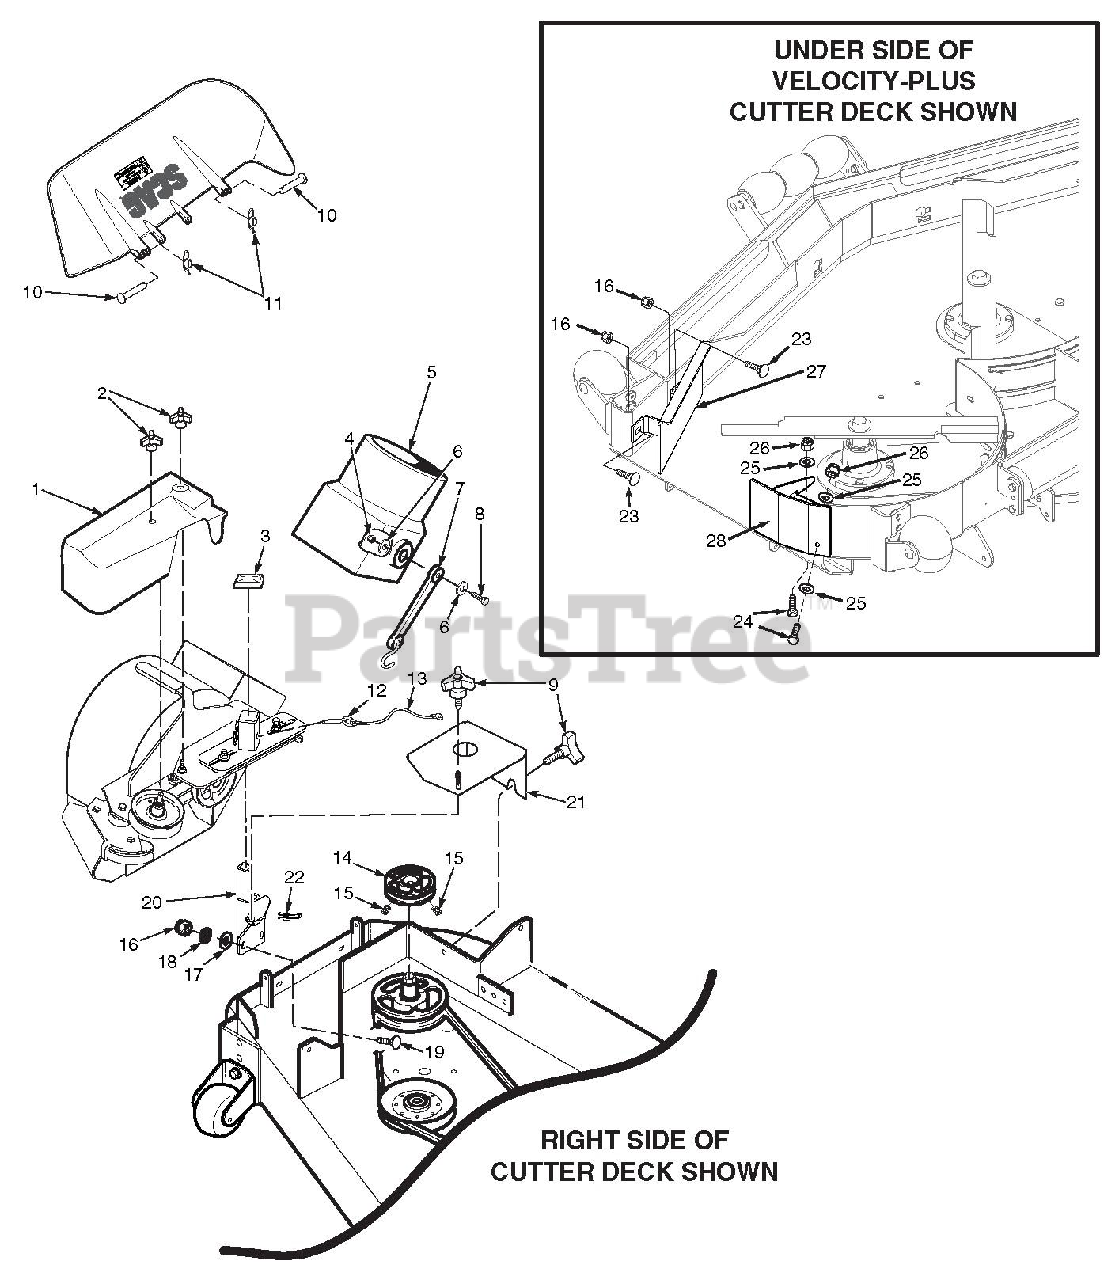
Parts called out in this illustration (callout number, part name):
1	Belt Cover, (61")
1	Belt Cover, (STT-52 & STTII-52)
2	Wingnut, Plastic 3/8" Small
3	Cap, Square Vinyl
4	Nut, Elastic Stop 1/4-20
5	Adapter, Blower
6	Flatwasher, 1/4-.312 x .750 x .065
7	Rubber Strap 7-3/4"
8	Bolt, Hex Head 1/4-20 x 1-1/4"
9	Knob W/Stud, 3/8-16 x 1-1/4"
10	Clevis Pin, 5/16 x 1-1/2"
11	Pin, Rue Cotter 5/16 Dia.
12	Pin, Ring 1/2 x 2-1/4"
13	Lanyard
14	Pulley, 5-1/2" Dia. - 1.125" Bore, (61")
14	Pulley, 4.0" Dia. - 1.125" Bore, (STT-52 & STTII-52)
15	Setscrew, 5/16-18 x 3/8"
16	Nut, Elastic Stop 3/8-16, (61")
16	Nut, Elastic Stop 1/2-13, (STT-52 & STTII-52)
17	Lockwasher, 3/8", (61")
18	Flatwasher, 3/8-.391 x .938 x .105, (61")
19	Bolt, Carr. 3/8-16 x 1-1/4" Grade 5
19	Bolt, Hex Head 1/2-13 x 1-1/2", (STT-52 & STTII-52)
20	Mounting Post Weldment, Blower, (61")
20	Mounting Post Weldment, Blower, (STT-52 & STTII-52)
21	Belt Cover Assembly w/Cap, (61")
21	Belt Cover, (STT-52 & STTII-52)
23	Bolt, Carriage 3/8-16 x 1"
24	Bolt, Hex Head 5/16-18 x 1"
25	Flatwasher, 5/16-.375 x .875 x .083
26	Nut, Elastic Stop 5/16-18
27	Baffle Weldment, 61V Deck
27	Baffle Weldment, 52V Deck
28	Baffle, Turbo 61" Deck
28	Baffle, Turbo 52" Deck
